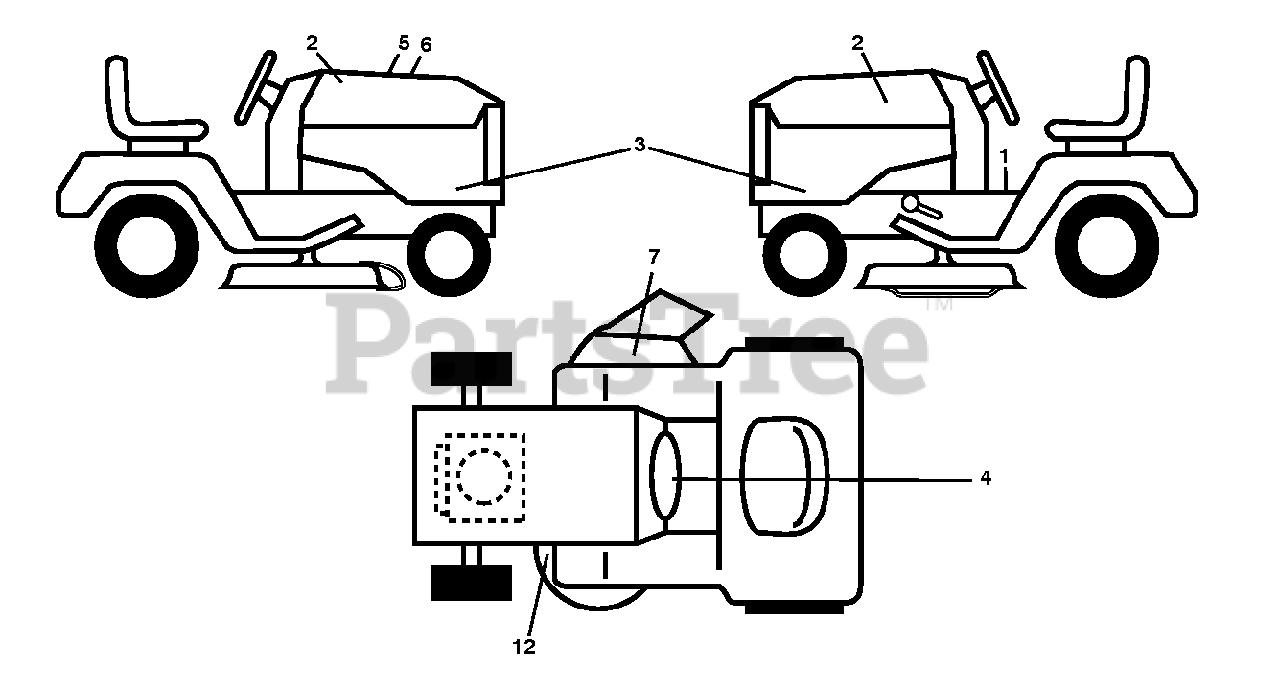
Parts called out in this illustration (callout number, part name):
1	DECAL.FENDER.WARNING.ENGLISH
2	Decal, WB 178MM 15 Husqvarna NEWBRAN
3	Decal, Side Panel YTH20K46 Set
4	DECAL, WARNING SPARK ARRESTOR
5	Warning Decal, Spark Arrest
6	Decal, Replacement Kohler KT7 TLW 46 K46AL
7	DECAL, DECK DEFLECTOR, WARNING
12	DECAL.V-BELT.SCH.42/46"MEC/ELE
